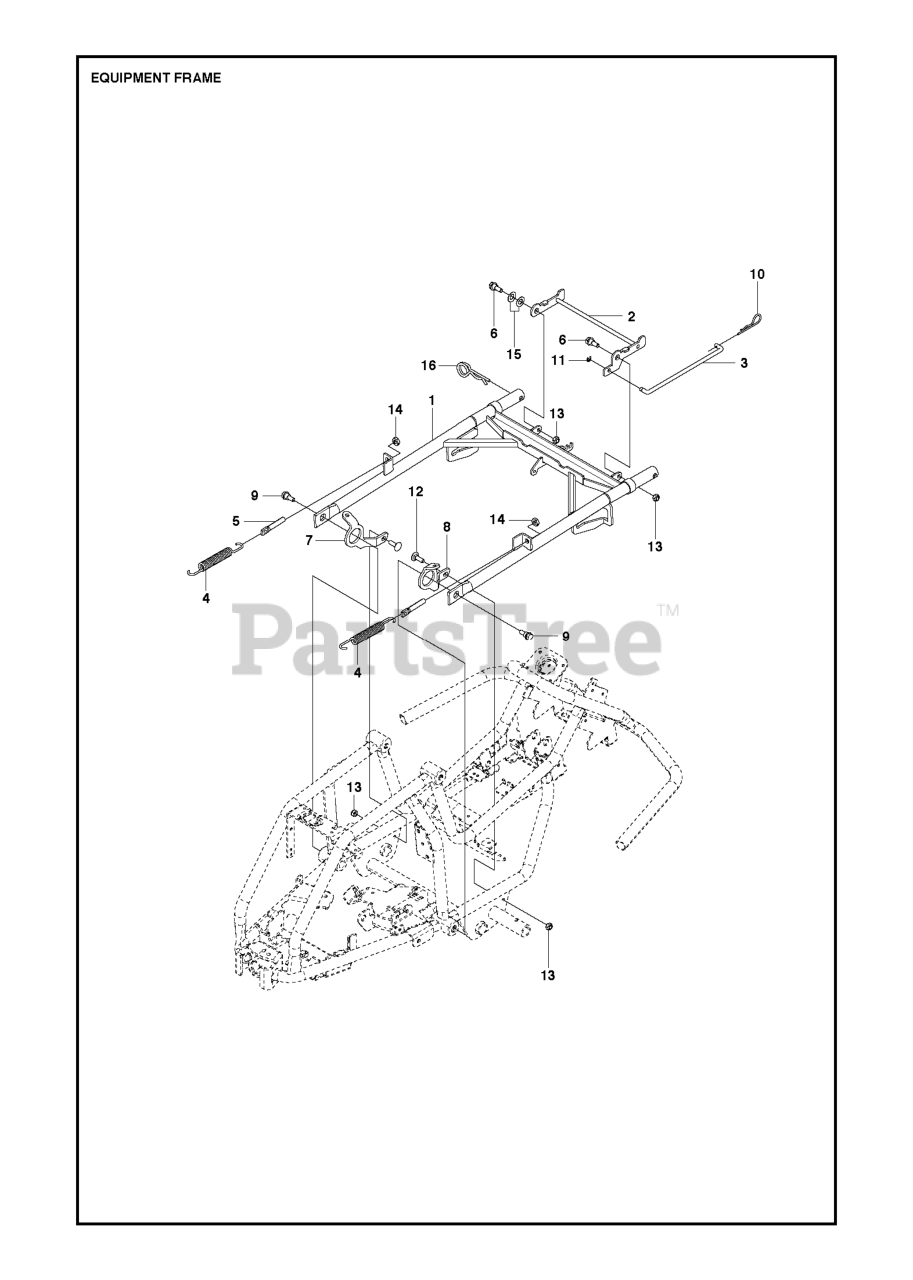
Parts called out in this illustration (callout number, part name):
1	EQUIPMENT FRAME ASSY
13	LOCKNUT M8
15	SPRINGWASHER
16	COTTER PIN
